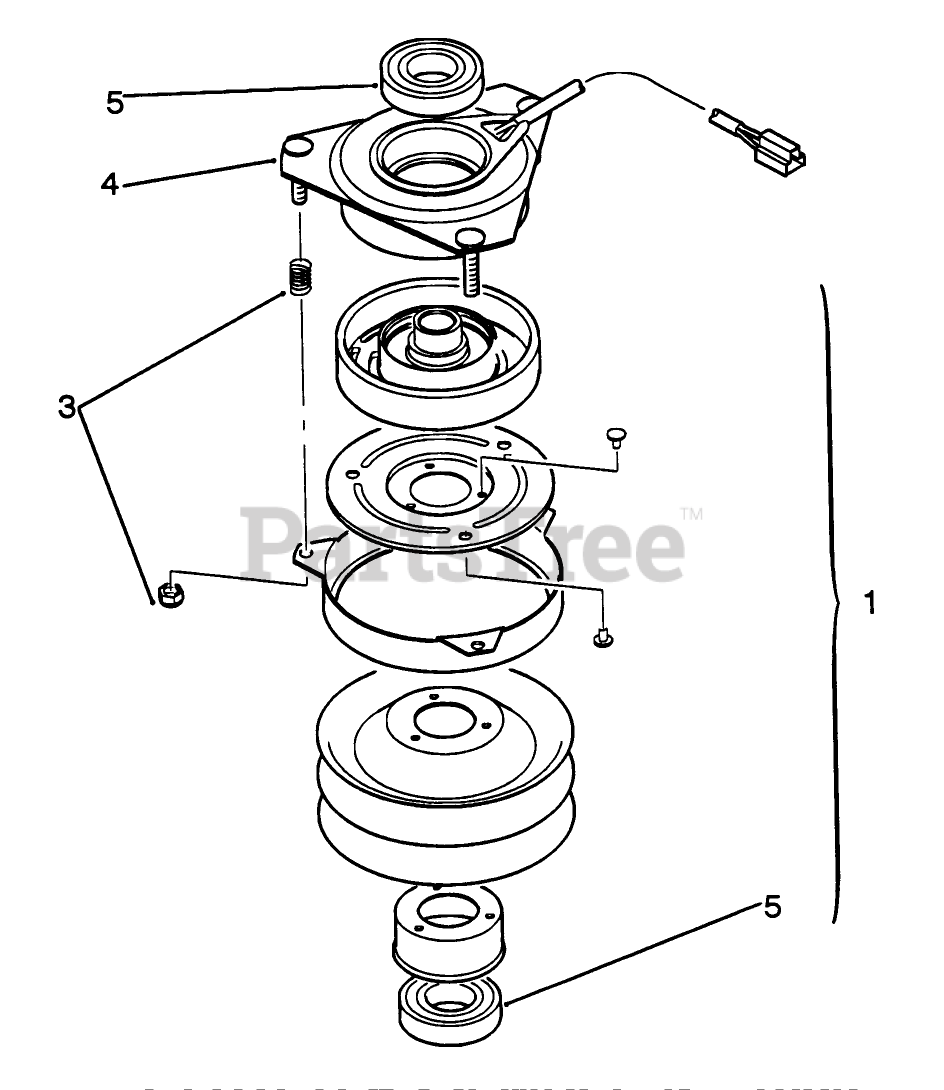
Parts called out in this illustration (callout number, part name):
1	Rotor, & Armature Ass-y (Incl. Ref. #5)
3	ACCESSORY PKG SRVC PART
4	Field Assembly (Incl. Ref. #5)
5	BEARING-ELEC CLUTCH
